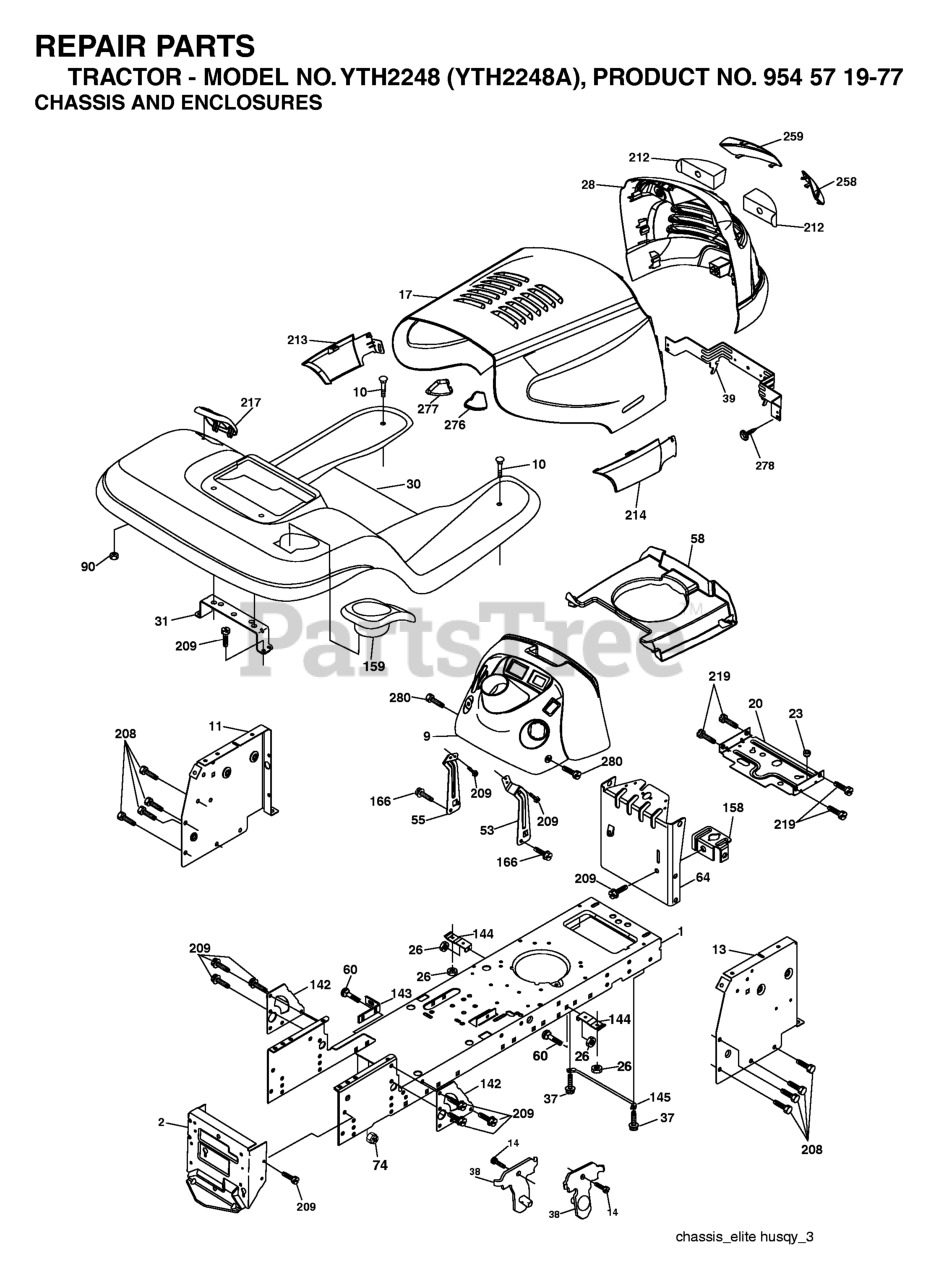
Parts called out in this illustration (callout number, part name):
1	CHASSIS STAMPING
2	DRAWBAR, 12GA
10	BOLT D
11	PANEL.DASH.LH.LTX
13	PANEL ASM, DASH RH
20	PLATE MTG.BATTERY/FUEL TANK
23	BUSHING.SNAP.NYL.BLK.
26	NUT
30	FENDER
31	BRACKET.SUPPORT.FENDER
37	Screw 5/16-18 x 1/2 Hex, Self Tapping 5/16-18 x 1/2
38	BRACKET.ASM.PIVOT.MOWER.REAR
39	BRACKET PIVOT LASER
58	AIR DUCT
60	Bolt - Rd. Hd. Sq. Neckiage 3/8 16 x 3/4
64	DASH LOWER
90	NUT.PUSH.3/16
142	PLATE REINFORCEMENT
143	BRACKET, SWAYBAR CHASSIS
144	BRKT, FOOT REST
145	ROD PIVOT CHASSIS/HOOD
158	BRACKET PARKING BRAKE
159	GREY CUP HOLDER
166	SCREW
208	SCREW 3/8-16X1/2
209	SCREW, 3/8-16X3/4
217	CONSOLE FUEL WINDOW
219	SCREW
280	SCREW THDROL 3/8-16 X 1-1/2
